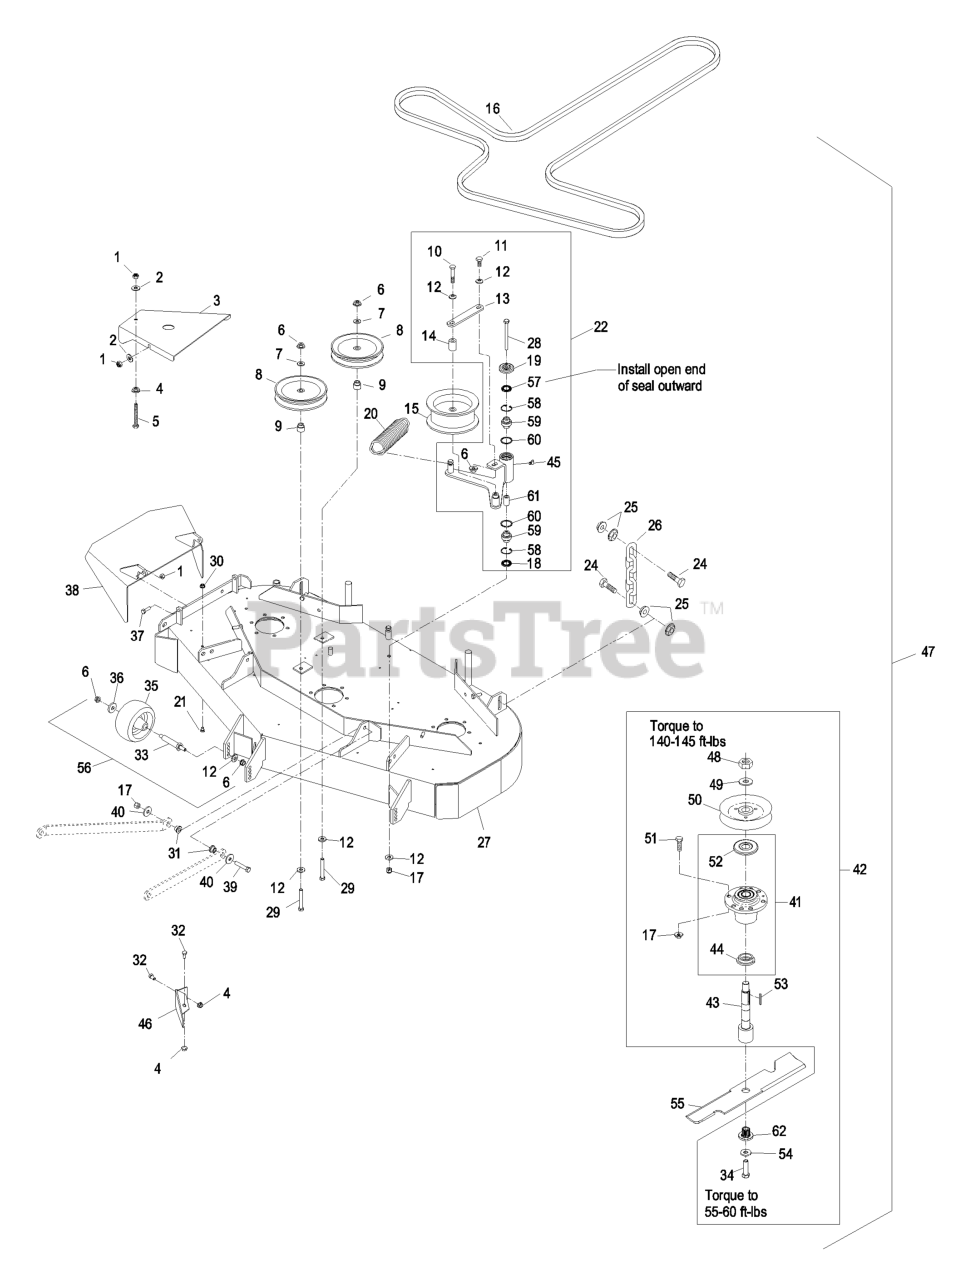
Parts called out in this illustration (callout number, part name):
1	NUT-LOCK, NI
2	WASHER-FLAT
3	SHIELD,BELT
5	BOLT,TAP HH
6	NUT-HHF, WHIZ
7	WASHER-FLAT
8	PULLEY-IDLER
9	BUSHING-IDLER
10	SCREW-HH
11	SCREW-HH
12	WASHER-BELLEVILLE
13	PLATE,GUIDE BELT (PLTD)
16	BELT - V, B
17	NUT-LOCK, NI
18	SEAL-LIP, DOUBLE
19	GUARD-TOP
21	SCREW-HH
22	KIT,DECK IDLER LHP/LCT
23	BUSHING-PIVOT, IDLER
24	SCREW-CAP, HH
26	CHAIN-LIFT, DECK
27	ASM,DECK W/DECALS LCT44
28	SCREW-HH
29	SCREW-HH
31	SPACER-STRUT
32	SCREW-HH
34	SCREW-HH
35	ROLLER-SCALP, ANTI
37	SCREW-HH
38	WLD,CHUTE 48
39	SCREW-HH
41	KIT, CUTTER HOUSING
42	ASM, CUTTER HSG 44
43	KIT, SPLINED SPINDLE 103-
44	SPACER-GUARD, BOTTOM
45	FITTING-GREASE, 90 DEG
47	Asm, Deck Complete (44")
48	NUT-HH
50	SHEAVE,W/HUB
51	SCREW-HH
52	GUARD-BEARING, TOP
53	KEY-RECTANGLE
54	WASHER-SPRING
57	SEAL-LIP, SINGLE
58	RING-SNAP
59	BEARING-SPHERICAL
62	BUSHING,SPLINED
